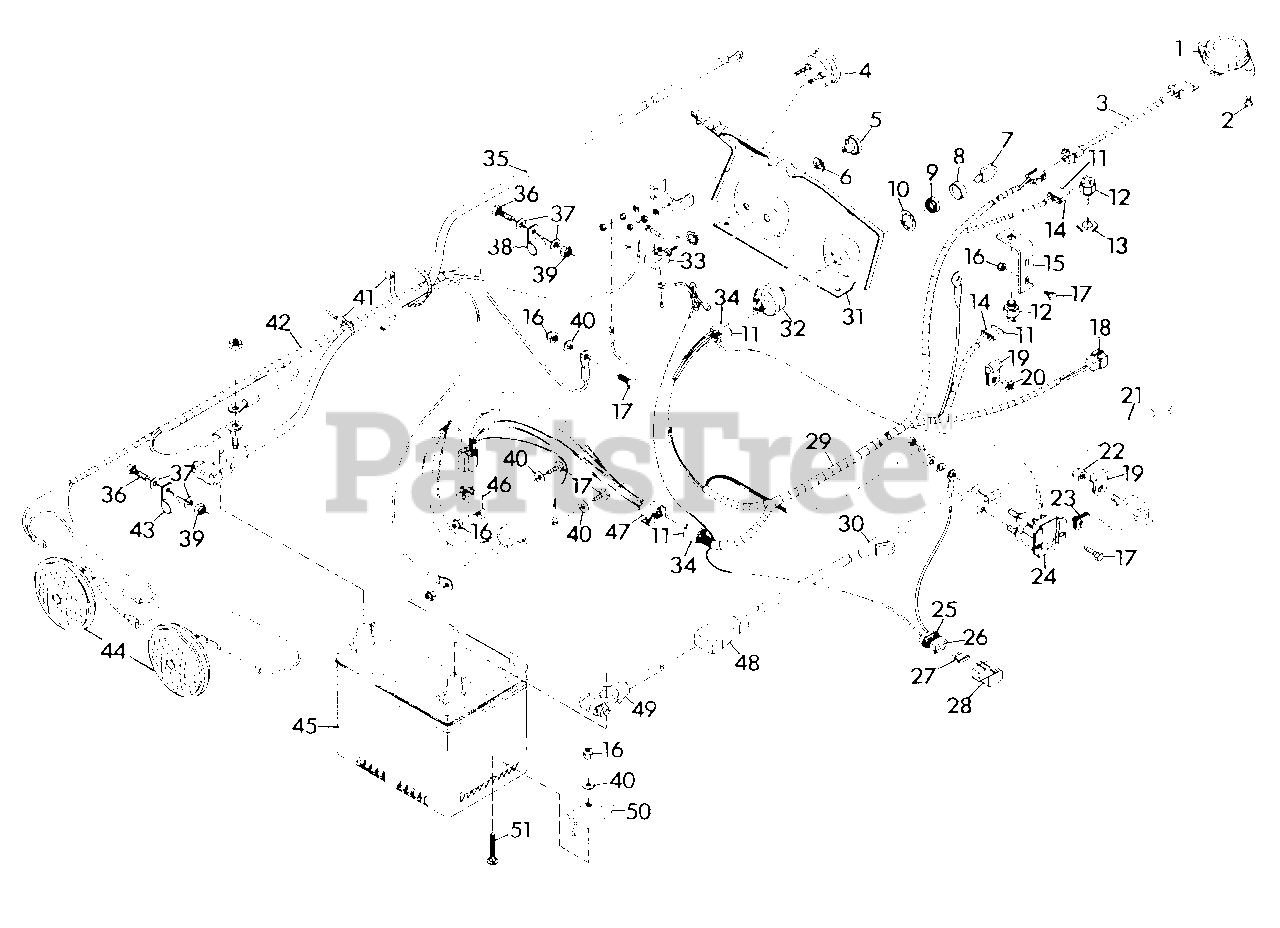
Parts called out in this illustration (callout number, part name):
1	SWITCH, SEAT
2	SCREW, MACHINE 1/4-20
3	HARNESS, WIRING SEAT SWITCH
4	GAUGE, AMMETER
5	KNOB, LIGHT SWITCH
6	NUT, SPECIAL LIGHT SWITCH
7	KEY, IGNITION SWITCH
8	BOOT, 9/16 SWITCH
9	NUT, JAM 9/16-24
10	WASHER, LOCK 9/16 INT. TOOTH
11	TERMINAL
12	SWITCH, INTERLOCK
13	NUT, STAMPED 9/16-18
14	CONNECTOR, 2-WIRE SWITCH
15	BRACKET, SWITCH
16	NUT, LOCK 1/4-20
17	BOLT, HEX 1/4-20X.75
18	CONNECTOR
19	CLAMP
20	NUT, LOCK 3/8-16
21	CABLE, STARTER
22	NUT, LOCK 3/8-16
23	NUT, SPEED 1/4-20
24	SWITCH, MAGNETIC
25	CONNECTOR
26	TERMINAL, 14-16 GAUGE
27	FUSE, 25 AMP
28	COVER
29	HARNESS, WIRING
30	BOOT, BATTERY CABLE
31	PANEL, INSTRUMENT
32	SWITCH, IGNITION
33	SWITCH, LIGHT
34	CONNECTOR
35	CABLE, NEGATIVE BATTERY
36	BOLT, HEX 5/16-18X1.00
37	WASHER, FLAT .344X.688X.065
38	CLAMP, NYLON
39	NUT, LOCK 5/16-18
40	WASHER, FLAT .281X.625X.065
41	TIE, CABLE
42	HARNESS, WIRING GROUND AND LIGHT
43	CLAMP, NYLON
44	HEADLIGHT
45	BATTERY, 12 VOLT
46	RELAY
47	MODULE, TIME DELAY
48	COVER, BATTERY TERMINAL
49	CABLE, BATTERY TO MAGNETIC SWITCH
50	CLAMP
51	BOLT, 1/4-20X1.75 RD HD SQ NK
